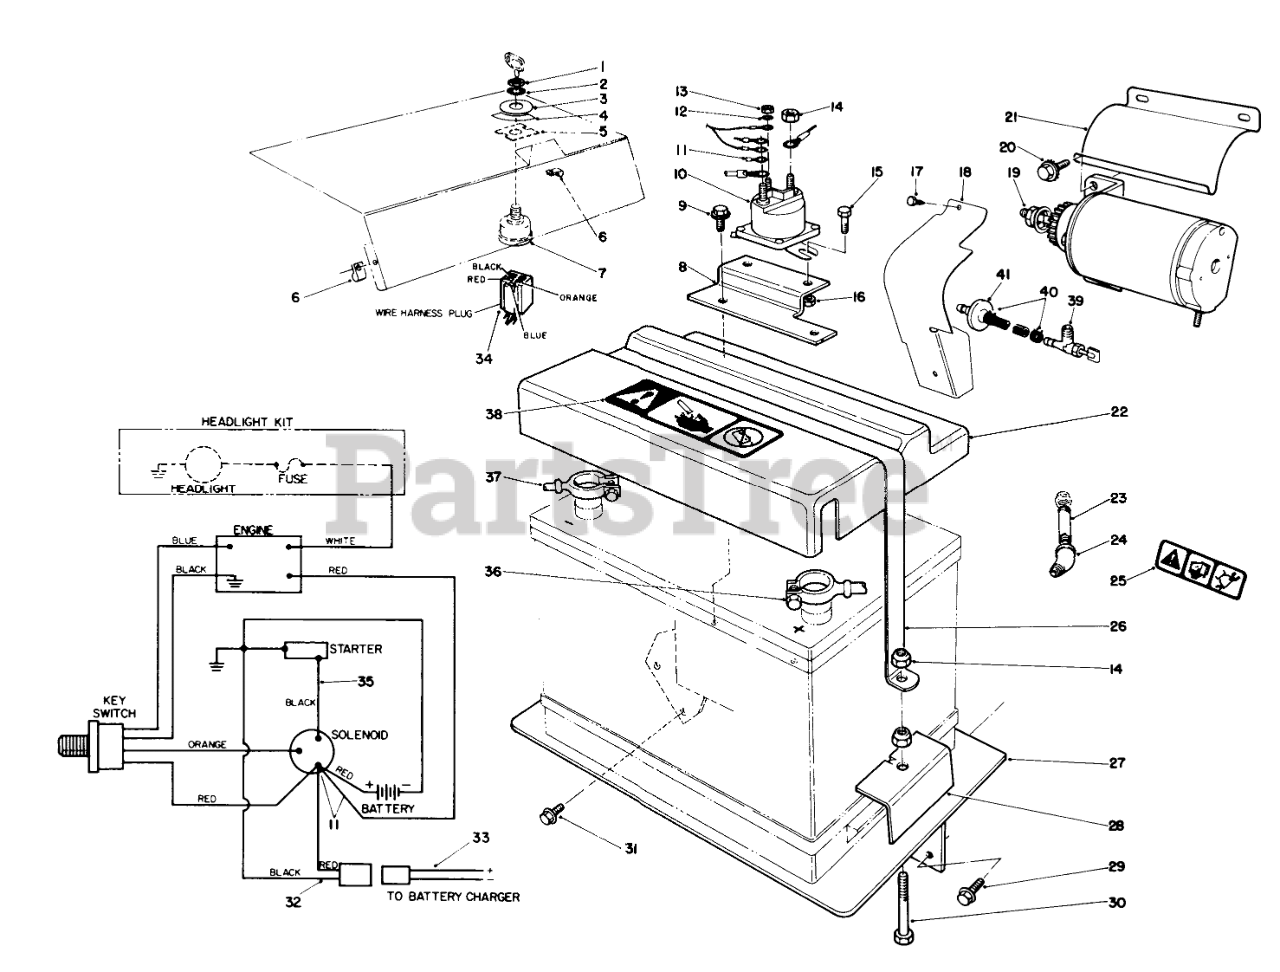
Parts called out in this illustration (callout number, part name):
1	NUT-HH
2	WASHER-TOOTH, INTERNAL
3	WASHER
4	DECAL
5	ADAPTER
6	R CLAMP
7	Switch-Starter (Incl.Ref. #1-2)
8	BRACKET
9	SCREW-HWH
10	SOLENOID
11	RING TONGUE TERMINAL
12	WASHER-LOCK, INT
13	NUT-HEX
14	NUT-LOCK, NI
15	SCREW-HH
16	NUT-LOCK, NI
17	Screw
18	Shield-Pinion
19	Starter Motor Ass-y
20	Crew
21	Shield-Dip
22	BATTERY COVER
23	NIPPLE 3/8NPTX 1.50
24	ELBOW
25	DECAL-WARNING
26	Strap Battery
27	Plate-Battery
28	BATTERY CLAMP
29	SCREW-HHF
30	SCREW-HH
31	SCREW-HHF
32	MALE WIRE ASM
33	FEMALE WIRE ASM
34	WIRE HARNESS
35	STRT MTR-SOLNOID WIRE
36	BATT-SOLENOID CABLE
37	KEY-SHIFT
38	DECAL
39	Valve-Fuel Tank
40	Clamp-Hose
41	Filter
